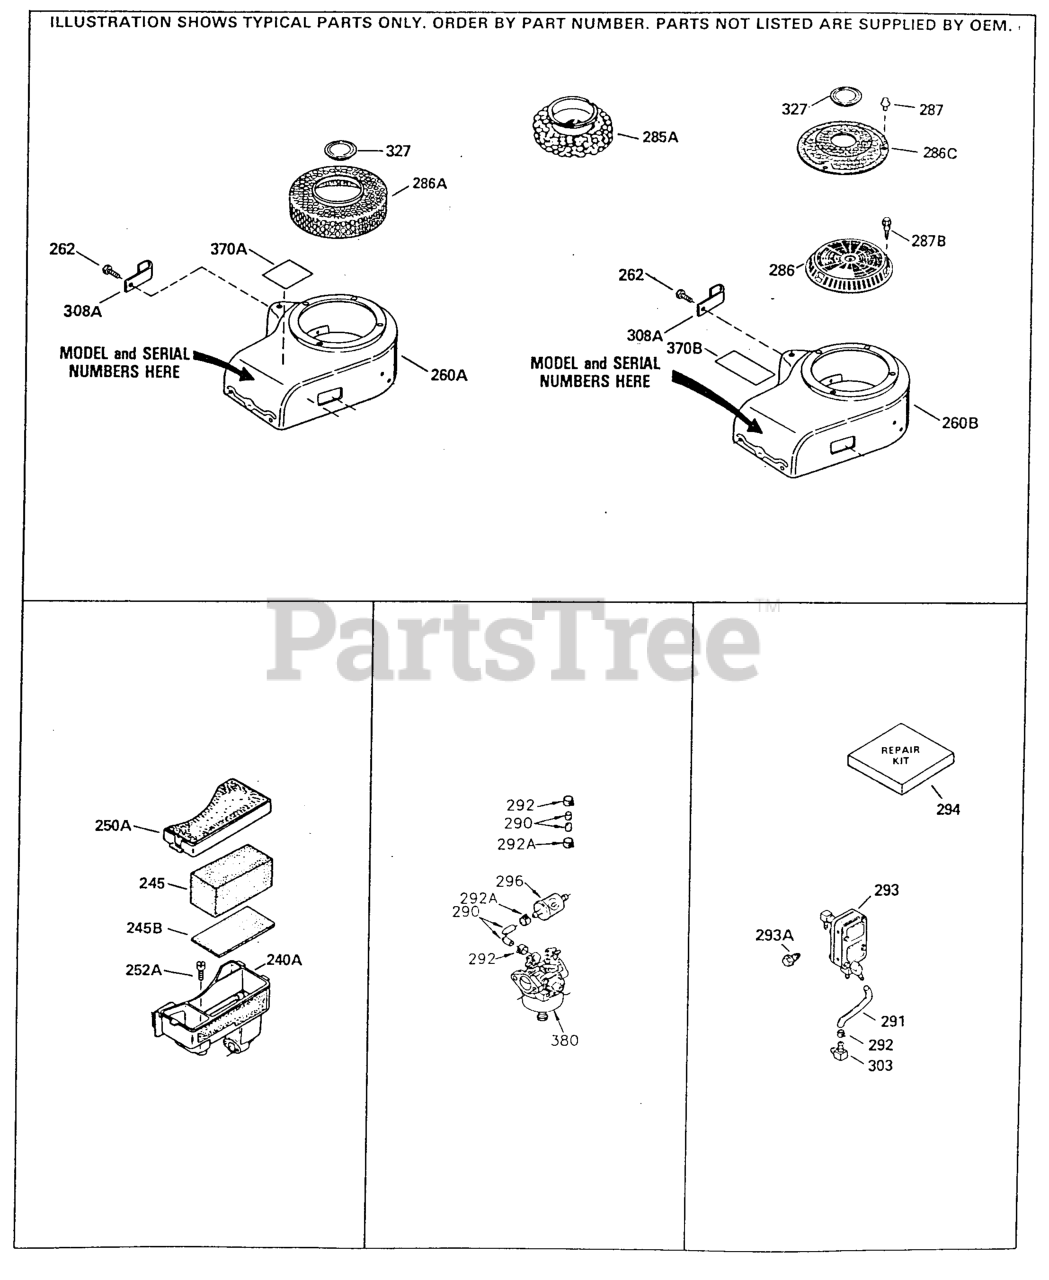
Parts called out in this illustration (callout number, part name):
245	AIR CLEANER
290	FUEL LINE
292A	CLAMP
296	FUEL FILTER
380	CARBURETOR
